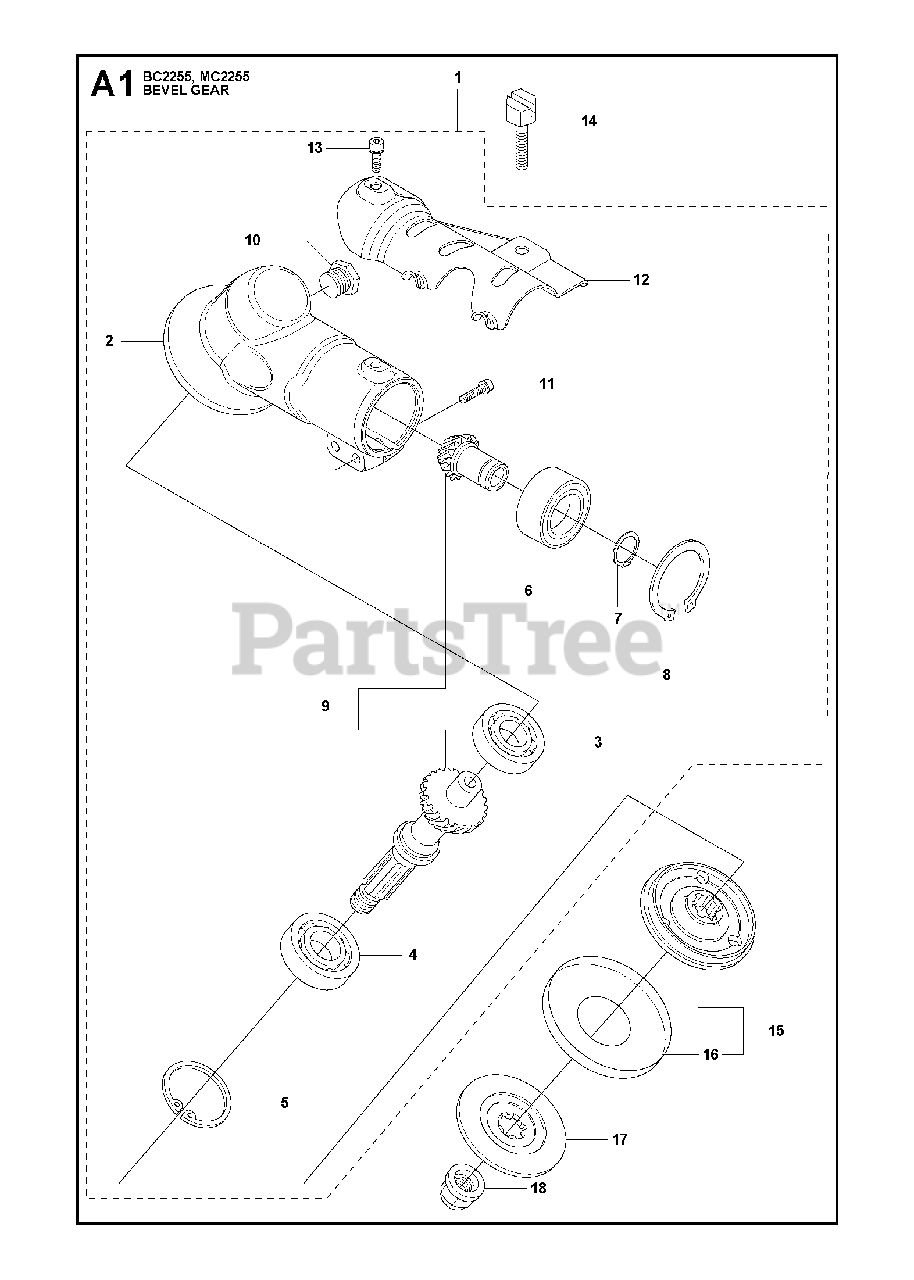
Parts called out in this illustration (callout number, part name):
2	GEAR HOUSING
3	BALL BEARING
5	RETAINING RING SGH 35
6	BEARING
7	RETAINING RING SGA 15
8	RETAINING RING
9	BEVEL GEAR
10	PLUG
11	SCREW
13	SCREW
15	RP CARRIER
16	GRASS SEALING
17	SUPPORT FLANGE
18	BLADE NUT
